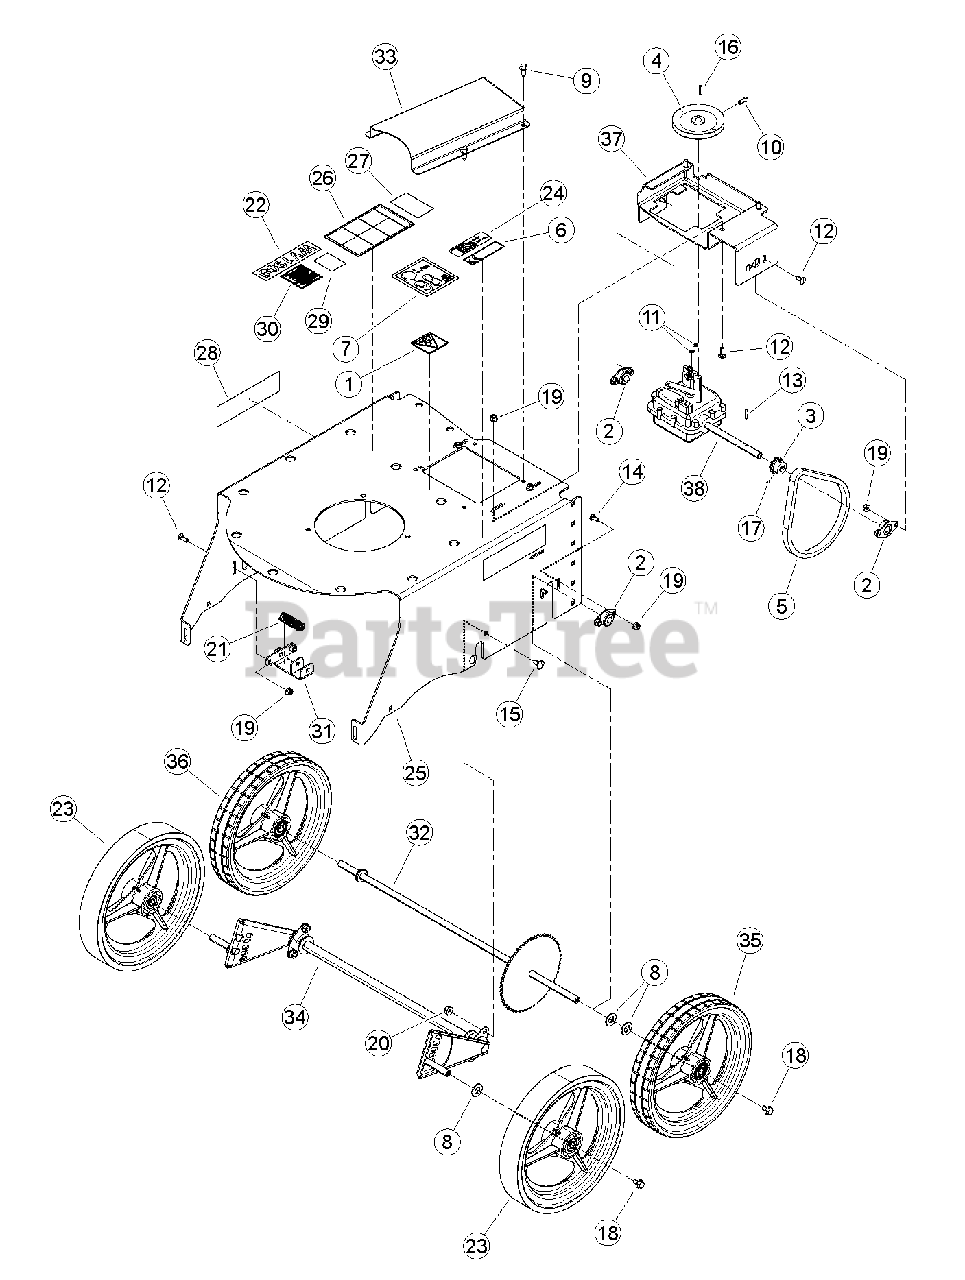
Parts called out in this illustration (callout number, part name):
1	DECAL, SHIELD DANGER ISO
2	BEARING, 1/2 FLANGE
3	SPROCKET, BEARVAC 35B10
4	PULLEY, 4 O.D. X 12 MM BORE
5	CHAIN, #35 X 62 PITCH W/ CONN. LINK
6	DECAL, 6HP SP BEARVAC INFORMATION (WV190S ONLY)
7	DECAL, 98 DB (WV190S ONLY)
8	WASHER, 1/2 SAE FLAT
9	SCREW, 11/32-12 X 7/8 FLANGE T-AB
10	SET SCREW, 1/4 X 5/8 SQ HD
11	WASHER, #8 SAE
12	BOLT, 1/4 X 3/4 GR5 CRG ZP
13	PIN, 1/8" X 7/8" SPRING
14	BOLT, 1/4 X 5/8 GR5 CRG NC ZP
15	BOLT, 5/16 X 5/8 GR5 CRG ZP
16	KEY, 4MM SQ X 20 MM
17	SCREW, #8-32 X 3/16 KNR CUP PT
18	BOLT, 5/16-18 X 1/2 G5 HH SERRATED FLANGE
19	NUT, 1/4-20 NYLOCK FLANGE
20	NUT, 5/16-18 NYLOCK FLANGE
21	SPRING, LC-072J06S COMPRESSION
22	DECAL, MODEL WV190S
23	WHEEL ASSEMBLY, BEARVAC PUSH
24	DECAL, ATLANTIC BRIDGE LTD INFO (WV190S ONLY)
25	ASSEMBLY, SELF VAC HOUSING W/ DECALS
26	DECAL, OPERATING INSTRUCTIONS ISO
27	DECAL, DANGER
28	DECAL, ECHO BEARCAT 6.82 X 1.90
29	DECAL, ECHO BEARCAT QR CODE
30	DECAL, SPARK ARRESTOR
31	WELDMENT, BEARVAC HEIGHT ADJ.
32	WELDMENT, SP LONG AXLE
33	GUARD, BEARVAC BELT
34	WELDMENT, AXLE PIVOT
35	WHEEL, BEARVAC SP LEFT
36	WHEEL, BEARVAC SP RIGHT
37	WELDMENT, TRANSMISSION MOUNT
38	TRANSMISSION, 3 SP. BEARVAC
